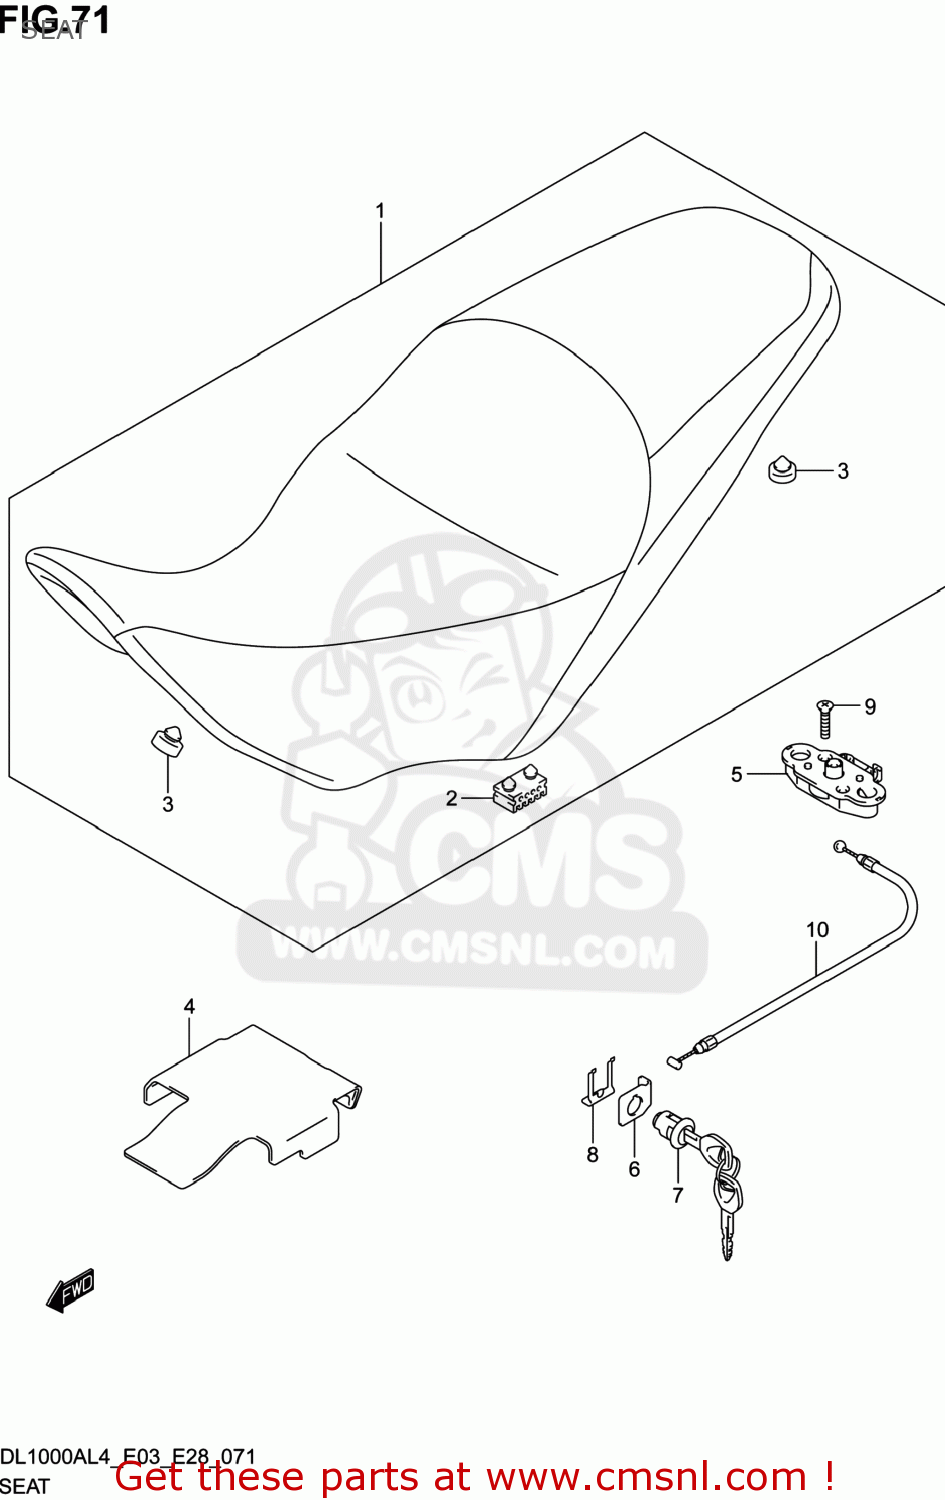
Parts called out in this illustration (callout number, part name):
1	SEAT ASSY
2	CUSHION,SEAT(40X20X15)
3	CUSHION
4	SHEET,HEAT SHIELD RUBBER
5	BRACKET,SEAT SUPPORT
6	GUIDE,SEAT LOCK CABLE
7	LOCK SET,SEAT
8	PLATE,SEAT LOCK ASSY
9	SCREW
10	CABLE,SEAT LOCK
